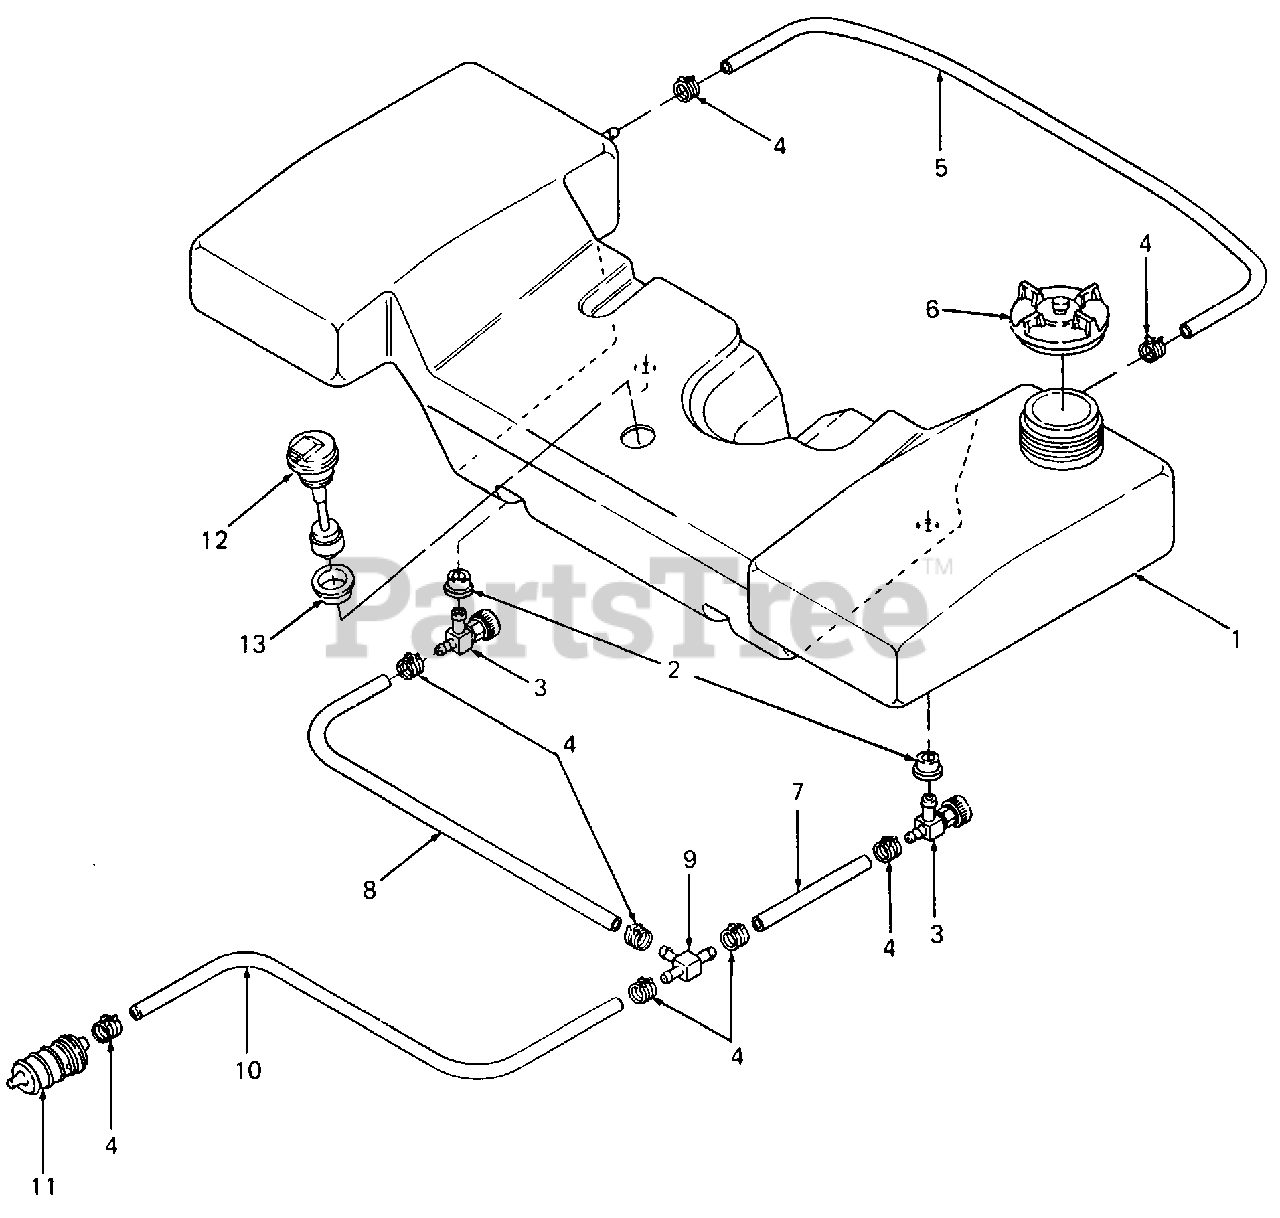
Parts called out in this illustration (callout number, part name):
1	Tank Assembly, Fuel
2	Bushing
3	Valve, Fuel Shutoff
4	Clamp, Hose
5	Line, Fuel -24" Lg
6	Cap, Fuel
7	Line, Fuel -5" Lg
8	Line, Fuel -19" Lg
9	T-Fitting
10	Line, Fuel -38" Lg
11	Filter, Fuel
12	Sensor, Low Fuel
13	Bushing, Rubber
